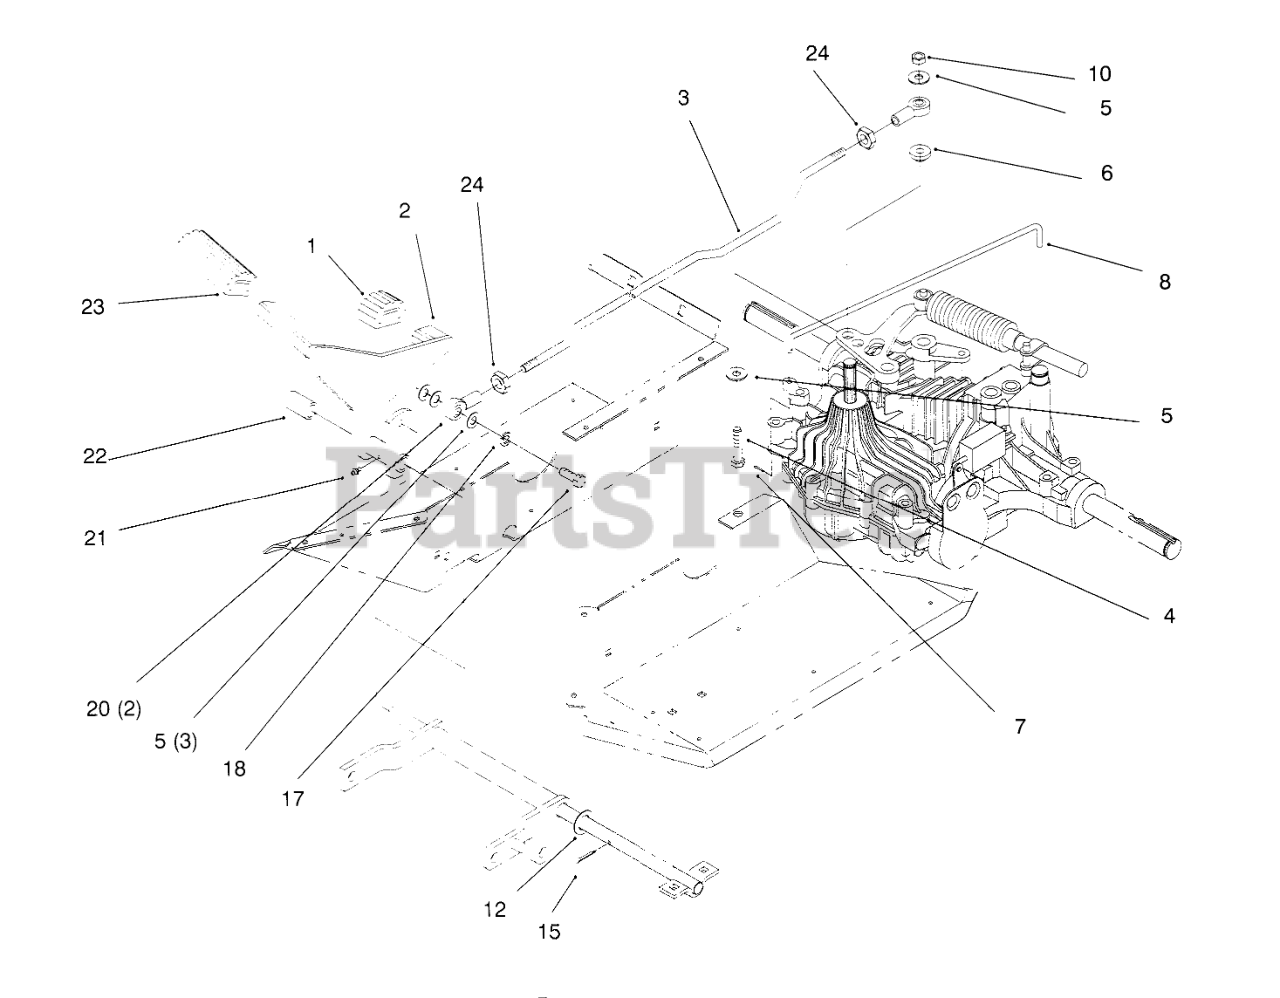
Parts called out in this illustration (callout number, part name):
1	Pad-Pedal Reverse (Only On: 72043,72063,72103)
2	Pedal-Hydro (Only On: 72043,72063,72103)
3	Rod (Only On: 72043,72063,72103)
4	Screw-HH (Only On: 72043,72063,72103)
5	WASHER-FLAT
6	Bushing (Only On: 72043,72063,72103)
7	Pin-Cotter (Only On: 72043,72063,72103)
8	Rod-Bypass (Only On: 72043,72063,72103)
10	Nut-Lock (Only On: 72043,72063,72103)
12	Washer-Flat (Only On: 72043,72063,72103)
15	Pin-Cotter (Only On: 72043,72063,72103)
17	Screw-HH (Only On: 72043,72063,72103)
18	Washer-Lock (Only On: 72043,72063,72103)
20	Rod End (Only On: 72043,72063,72103)
21	Fitting-Grease (Only On: 72043,72063,72103)
22	Spacer-Hydro Pedal (Only On: 72043,72063,72103)
23	Pad-Pedal Forward (Only On: 72043,72063,72103)
24	Nut-HJ (Only On: 72043,72063,72103)
